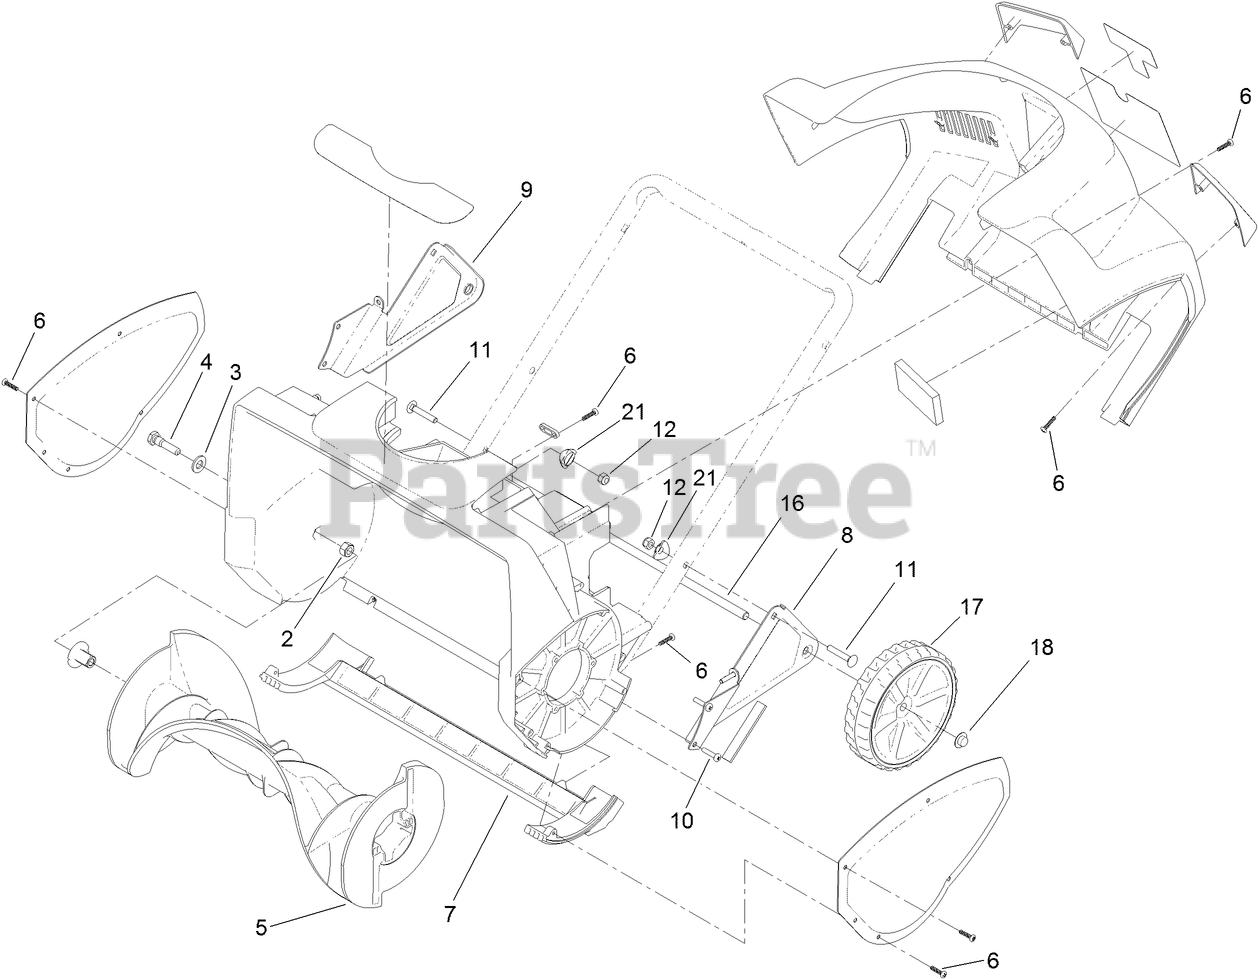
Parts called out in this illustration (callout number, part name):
3	WASHER-FLAT
4	PIN-ROTOR
5	ROTOR ASM
6	SCREW-PPH
8	BRACKET-WHEEL, LH
9	BRACKET-WHEEL, RH
10	SCREW-PPH
11	BOLT-CARR
17	WHEEL ASM
21	WASHER-CUP
